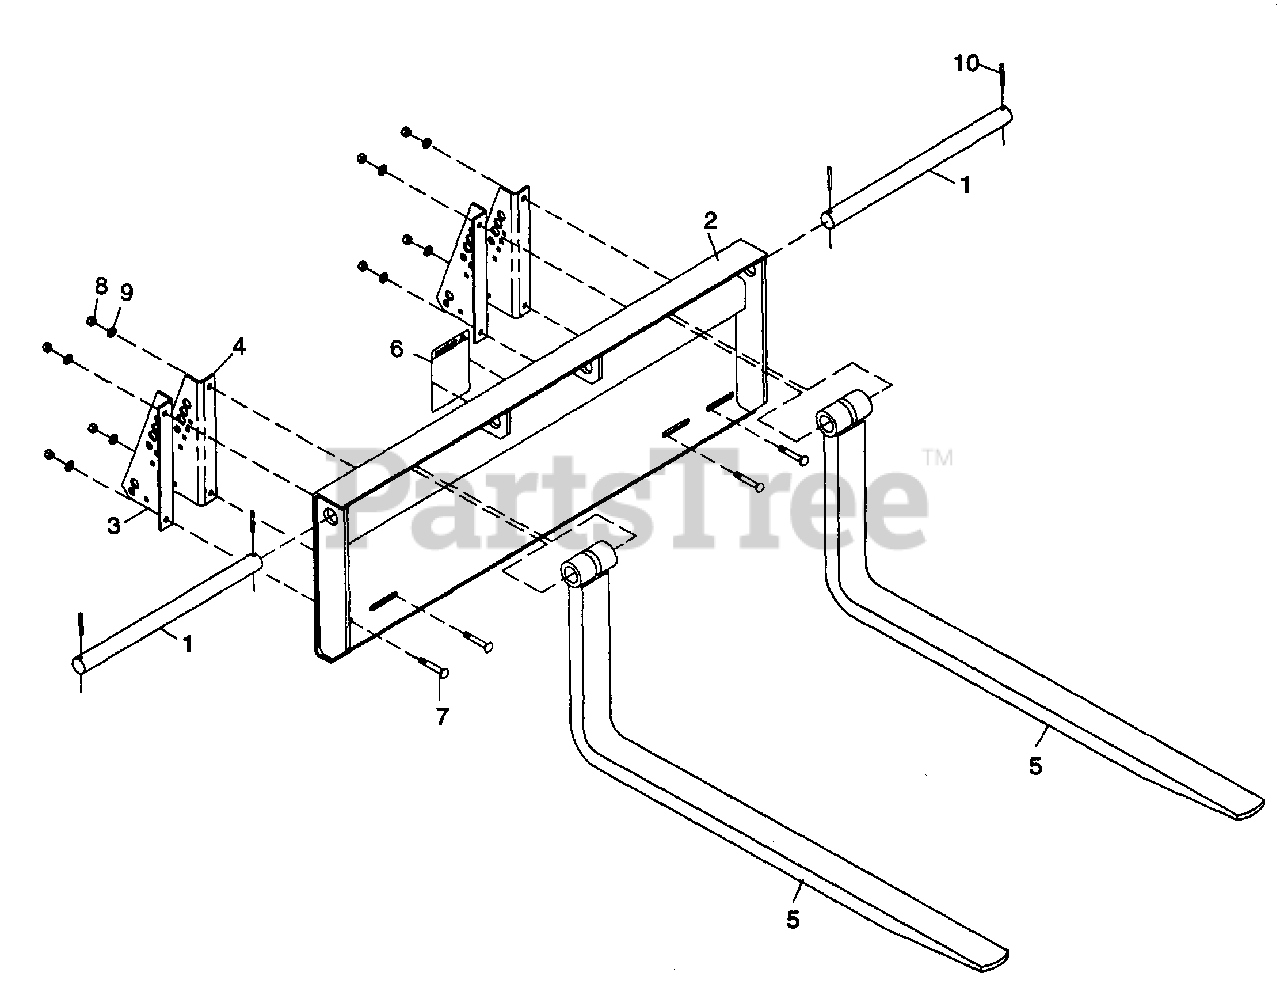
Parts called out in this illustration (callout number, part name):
1	Pivot rod
2	Back plate
3	Attach angle, right hand
4	Attach angle, left hand
6	Warning decal
7	1/2 NC x 1-1/4 Carriage bolt plated
8	1/2 NC Hex nut plated
9	1/2 Standard lockwasher
10	1/4 x 2 Roll pin
